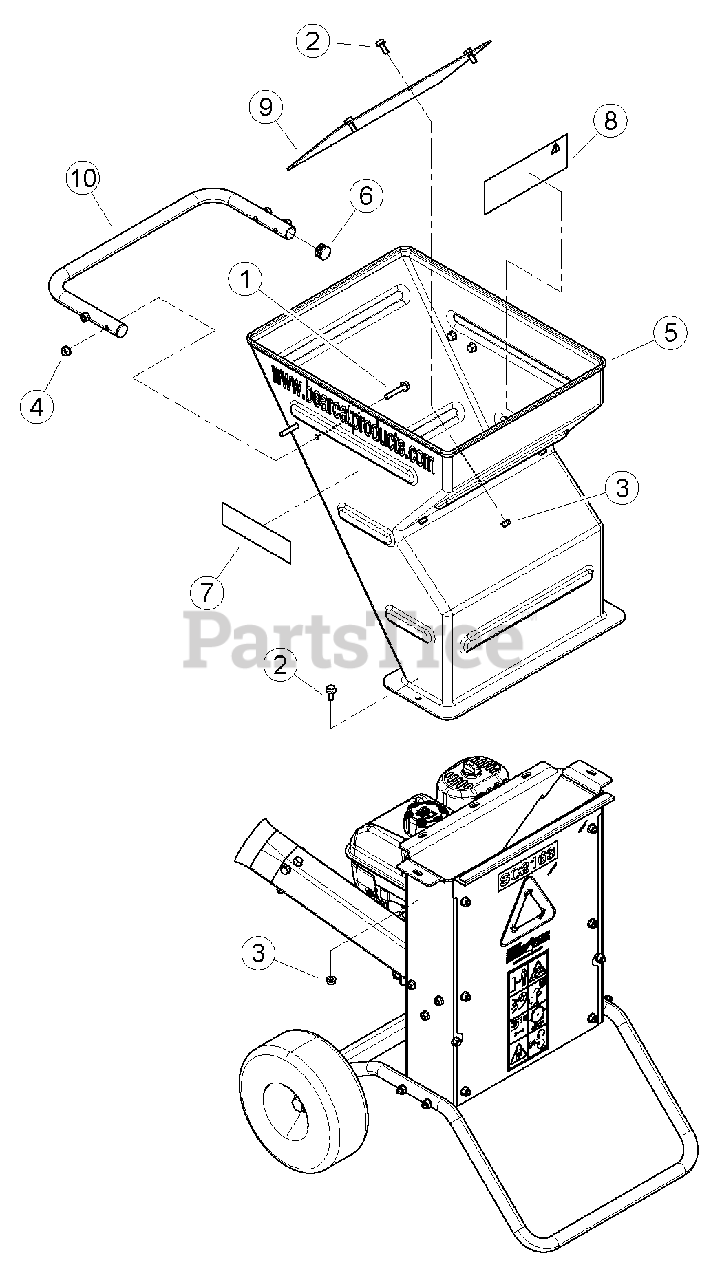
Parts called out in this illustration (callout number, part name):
1	BOLT, 5/16 X 1-3/4 FLANGE NC
2	BOLT, 5/16 X 3/4" SERRATED FLANGE GR5 ZP
3	NUT, 5/16 SPIRAL LOCK
4	NUT, 5/16-18 NYLOCK FLANGE
5	HOPPER, 2 INCH SHREDDER/CHIPPER
6	PLUG, 1" ROUND RIBBED
7	DECAL, ECHO BEARCAT 6.82 X 1.90 (WHITE)
8	DECAL, MANUAL INFORMATION
9	FLAP, SHREDDER HOPPER
10	HANDLE, SC2163
